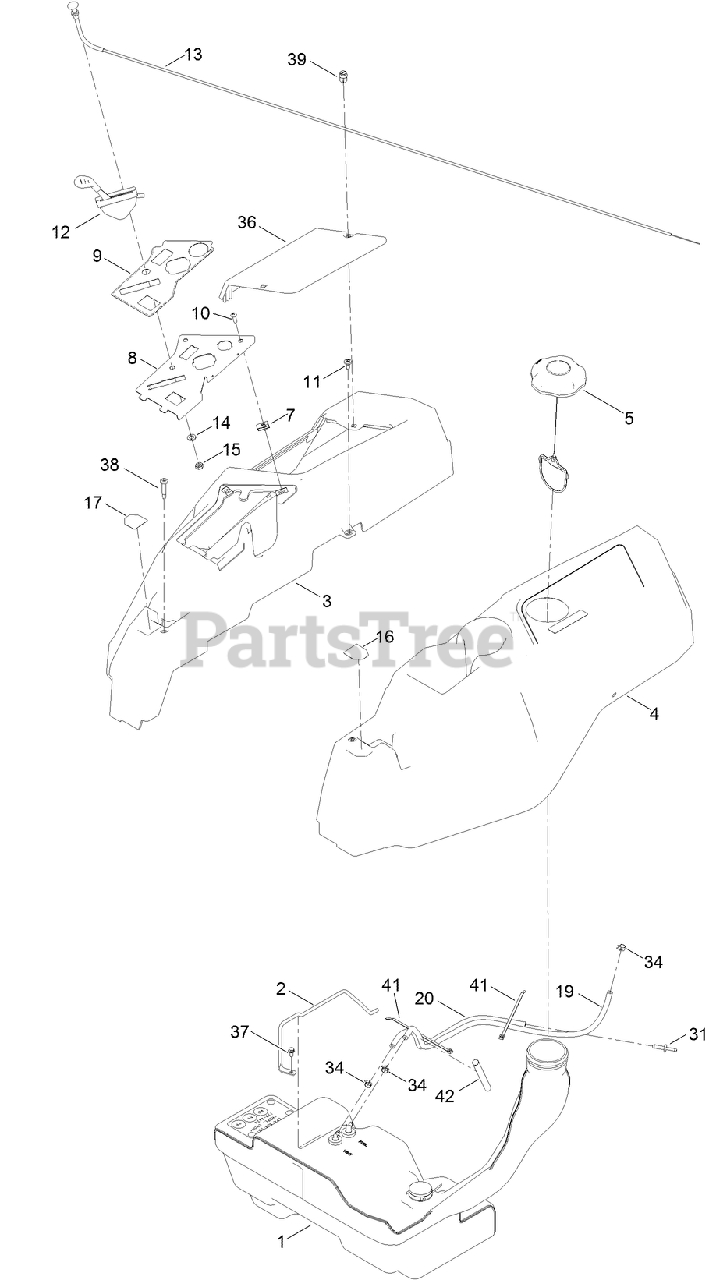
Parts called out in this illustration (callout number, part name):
1	FUEL TANK ASM
2	ROD-HOLD DOWN
3	POD-RH
4	POD-LH
5	CAP-FUEL, RATCHETING
8	PANEL-CONTROL
9	DECAL-CONTROL W/CHOKE
10	SCREW-PRH
11	SCREW-SHOULDER
12	CABLE-THROTTLE
13	CABLE-CHOKE
14	WASHER-LOCK
15	NUT-HJ
16	DECAL-LEVER, CONTROL (LH)
17	DECAL-LEVER, CONTROL (RH)
19	HOSE-FUEL
20	HOSE-FUEL
31	ADAPTOR-ORIFICE
34	CLAMP-HOSE
36	COVER-BATTERY
37	SCREW-HWH
38	SCREW-SHOULDER
39	FASTENER
41	TIE-CABLE
